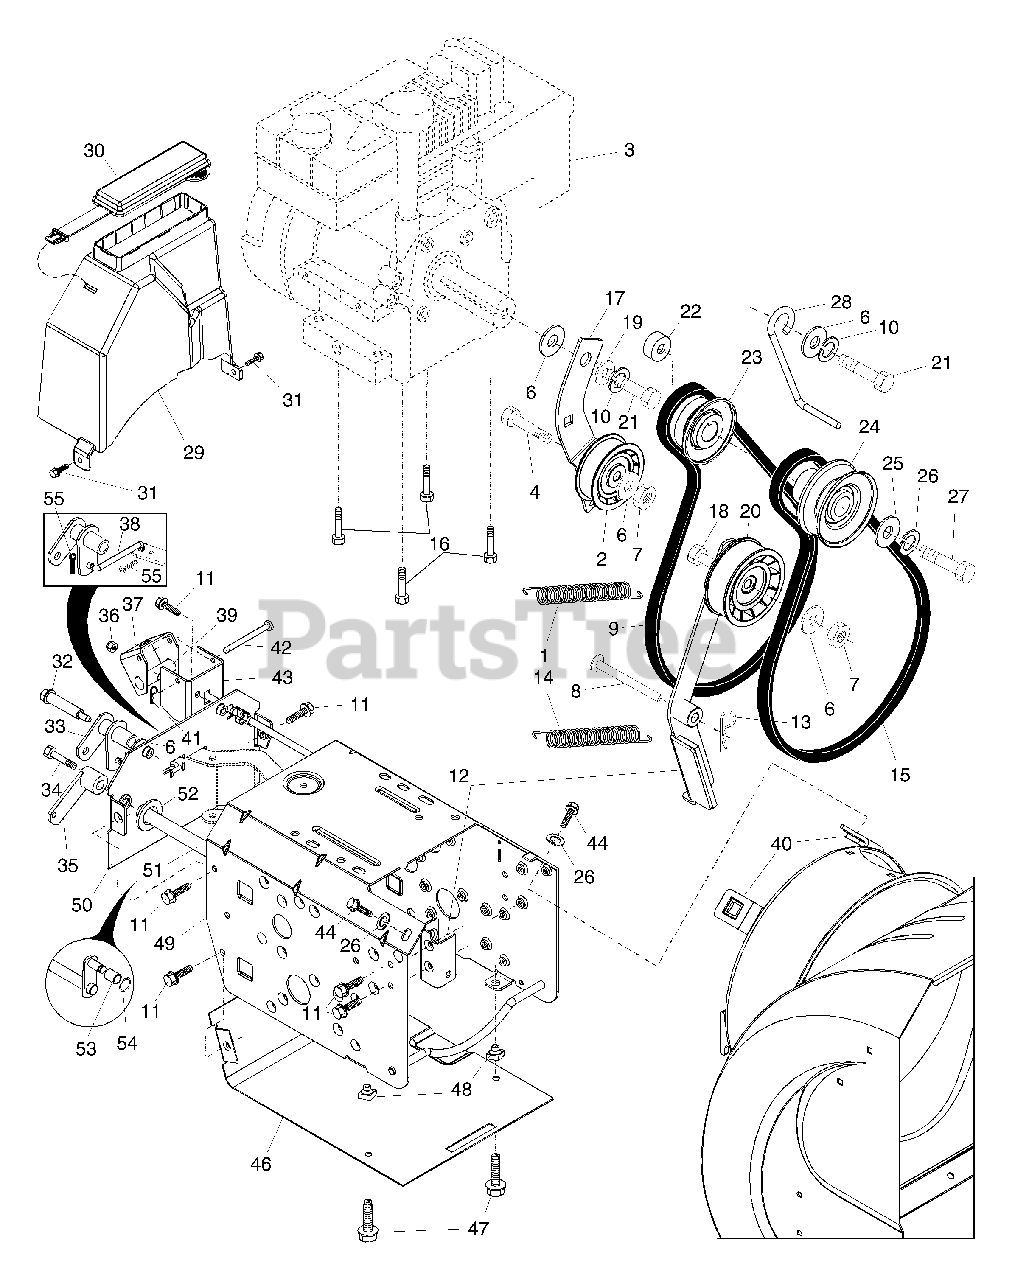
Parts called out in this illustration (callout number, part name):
1	Spring, Traction Idler
2	Pulley, Idler (2-1/4)
4	Screw, Hex Head 5/16-18 x 1-1/4
6	Washer, Flat
7	Nut, Jam, Lock 5/16-18
8	Pin, Idler Pivot
9	V-Belt, Traction Drive
10	Washer, Lock 5/16
11	Screw, Hex Head 5/16-18 x 3/4
12	Impeller Idler Arm & Bracket Assembly
13	Retainer, Hairpin
14	Spring, Brake
15	V-Belt, Impeller Drive
16	Screw, Hex Head 3/8-16 x 1-1/4
17	Arm, Idler
18	Screw, Hex Head 5/16-18 x 1-1/2
19	Bushing, Idler Pivot
20	Pulley, Idler (2-3/4)
21	Screw, Hex Head 5/16-18 x 1
22	Spacer, Engine Pulley
23	Pulley, Engine, Traction Drive
24	Pulley, Engine, Impeller Drive
25	Washer, Flat 3/8
26	Washer, Lock 3/8
27	Screw, Hex Head 3/8-24 x 1-3/8
28	Guide, Belt
29	Cover, Belt
30	Cover, Toolbox
31	Screw, Hex Head 1/4-20 x 1/2
32	Bolt, Shoulder 5/16-18
33	Bellcrank Shifter
34	Screw, Hex Head 1/4-28 x 3/4
35	Arm, Auger Control
36	Nut, Lock 5/16-18
37	Bellcrank Assembly
38	Link, Speed Control
39	Trunnion, Pivot Bracket
40	Nut, Cage 3/8-16
41	Pin, Cotter 1/16 x 1/2
42	Pin, Pivot Bracket
43	Bracket, Bellcrank
44	Screw, Hex Head 3/8-16 x 1-1/2
46	Pan, Frame Bottom
47	Screw, Hex Head 5/16-18 x 3/4
48	Nut, Speed 5/16-18
49	Frame Assembly
50	Plate, Frame End
51	Shaft, Auger Control
52	Washer, Hardened
53	Roller
54	Ring, Retaining
55	Clip, Retainer
